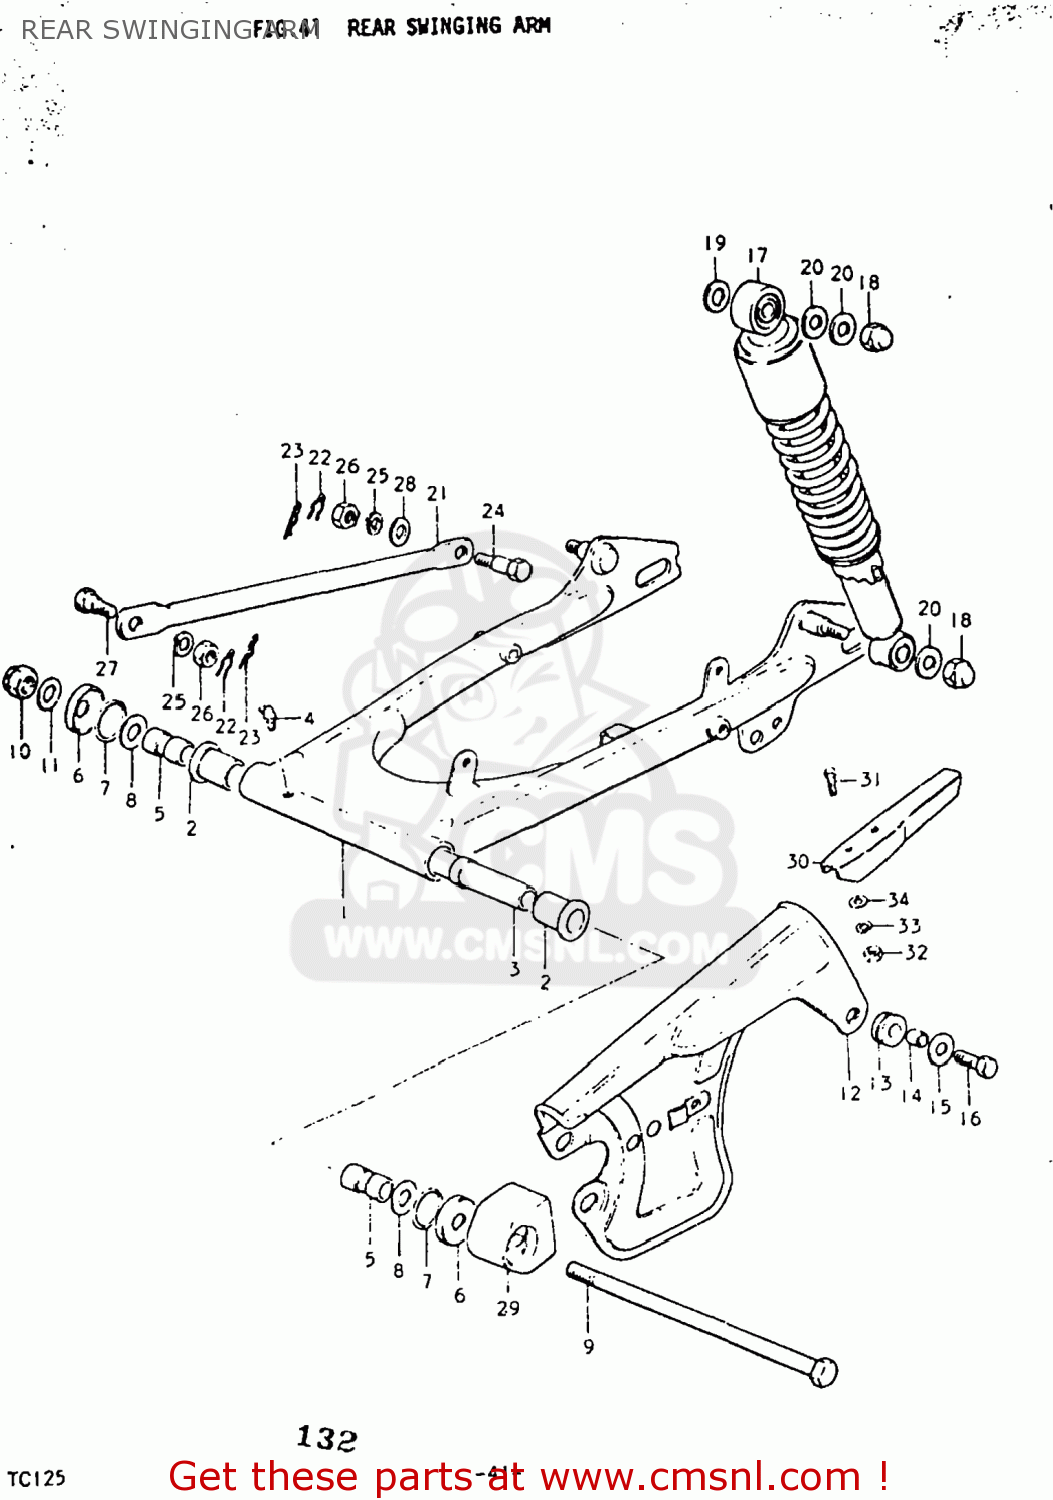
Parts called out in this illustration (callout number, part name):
1	SWING ARM ASSEMBLY,REAR
2	BUSH
3	SPACER,SWING ARM,CENTER
4	NIPPLE,GREASE
5	SPACER,RR SWGARM PIVOT
6	COVER,SWGARM BUSH DUST SEAL
7	O RING(D:2,ID:24.5)
8	WASHER(12.5X24X2.3)
9	SHAFT,PIVOT
10	NUT
11	WASHER
12	CASE,CHAIN
13	CUSHION
14	SPACER (7X9X7)
15	WASHER (6.5X20X1.2)
16	BOLT
17	ABSORBER ASSEMBLY,REAR SHOCK
18	NUT
19	WASHER
20	WASHER
21	TORQUE LINK,REAR
22	RETAINER,SNAP
23	CLIP
24	BOLT(8X26.5)
25	LOCK WASHER
26	NUT
27	BOLT(8X22)
28	WASHER
29	BUFFER,CHAIN TOUCH DEFENSE
31	BOLT
32	NUT
33	LOCK WASHER
34	WASHER
